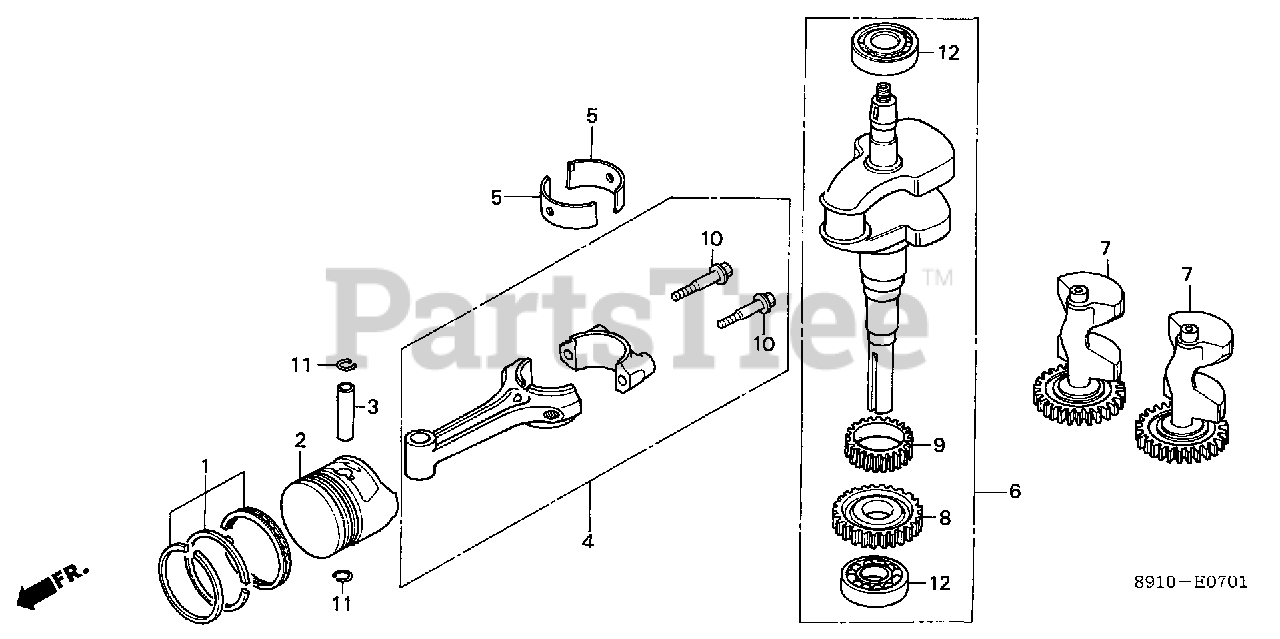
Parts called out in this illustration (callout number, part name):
1	RING SET, PISTON (STD)
1	RING SET, PISTON (STD) (NOT AVAILABLE)
1	RING SET, PISTON (OVER SIZE)
1	RING SET, PISTON (0.25)
1	RING, PISTON (OVER SIZE)
1	RING SET, PISTON (0.50)
1	RING SET, PISTON (0.75)
2	PISTON (STD)
2	PISTON (0.25)
2	PISTON (0.50)
2	PISTON (0.75)
3	PIN, PISTON
4	ROD ASSY., CONNECTING
5	BEARING A, CONNECTING ROD
5	BEARING B, CONNECTING ROD
5	BEARING C, CONNECTING ROD
5	BEARING D, CONNECTING ROD
5	BEARING E, CONNECTING ROD
6	CRANKSHAFT (NOT AVAILABLE)
7	WEIGHT, BALANCER
8	GEAR, BALANCER
9	GEAR, TIMING (28T)
10	BOLT, CONNECTING ROD (8MM)
11	CLIP, PISTON PIN (19MM)
12	BEARING, RADIAL BALL (6206)
